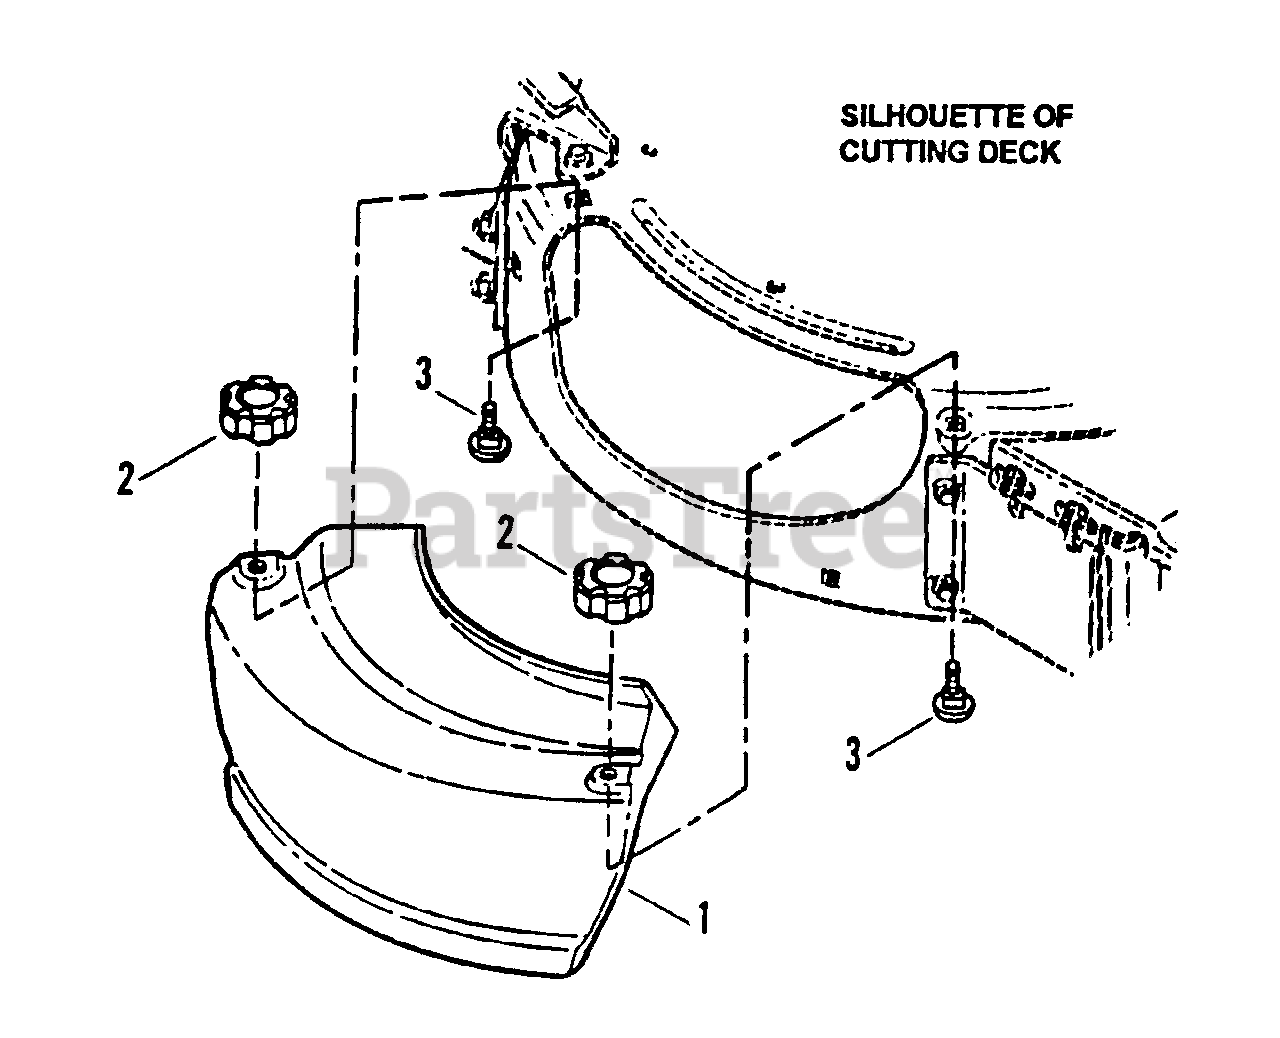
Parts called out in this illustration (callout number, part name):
1	COVER, Recycling
2	KNOB, Fluted, 5/16-18 Thread
3	BOLT, 5/16-18 x 3/4 Short Neck Carriage, Grade 5
